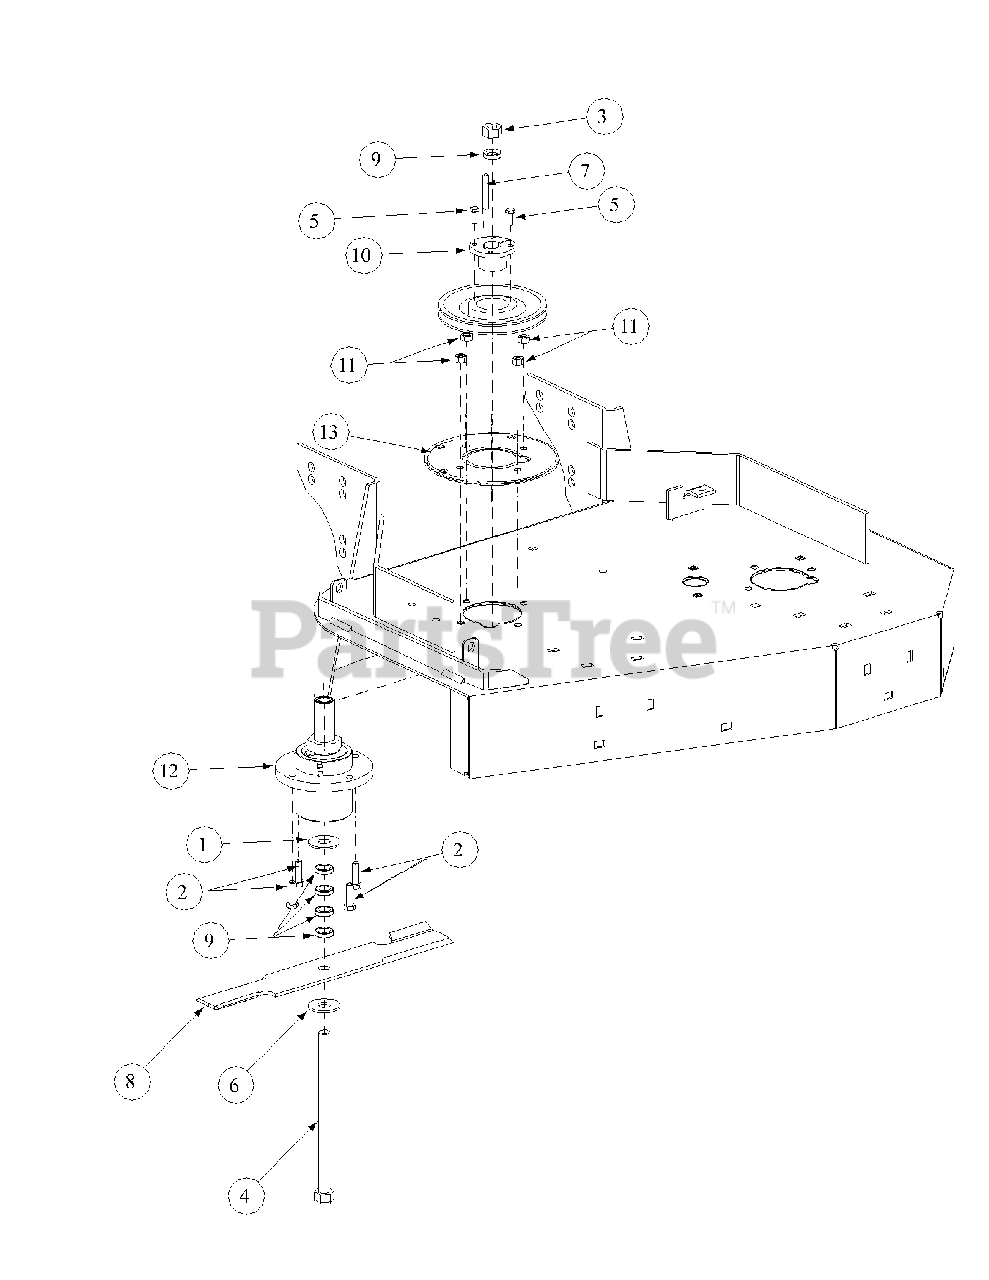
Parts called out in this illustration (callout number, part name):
1	Flat Washer, 1-1/2 x 5/8 x .05
2	Hex Cap Screw, 3/8-16 x 1-1/4
3	Hex Nut, 5/8-11
4	Hex Cap Screw, 5/8-11 x 9-1/2
5	Hex Cap Screw, 1/4-20, .75
6	Flat Washer, 5/8 Zinc
7	Key Stock, 1/4 x 1/4 x 2
8	Rotary Blade, 16-1/2
9	Blade Spacer, 5/8 ID, 1/4 Thick
11	Lock Nut, 3/8-16
12	Spindle Assembly
13	Spindle Backing Plate
